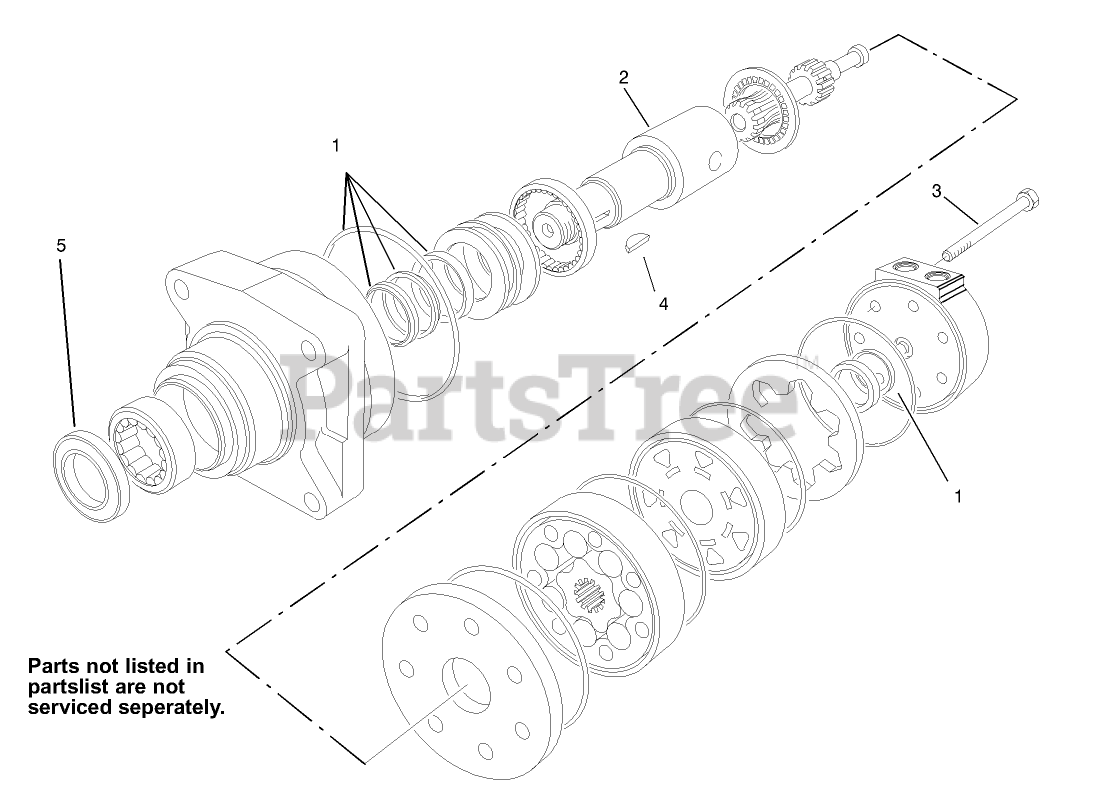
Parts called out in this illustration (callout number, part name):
1	SEAL KIT
2	SHAFT-COUPLING
3	SCREW-HH
4	KEY-WOODRUFF
